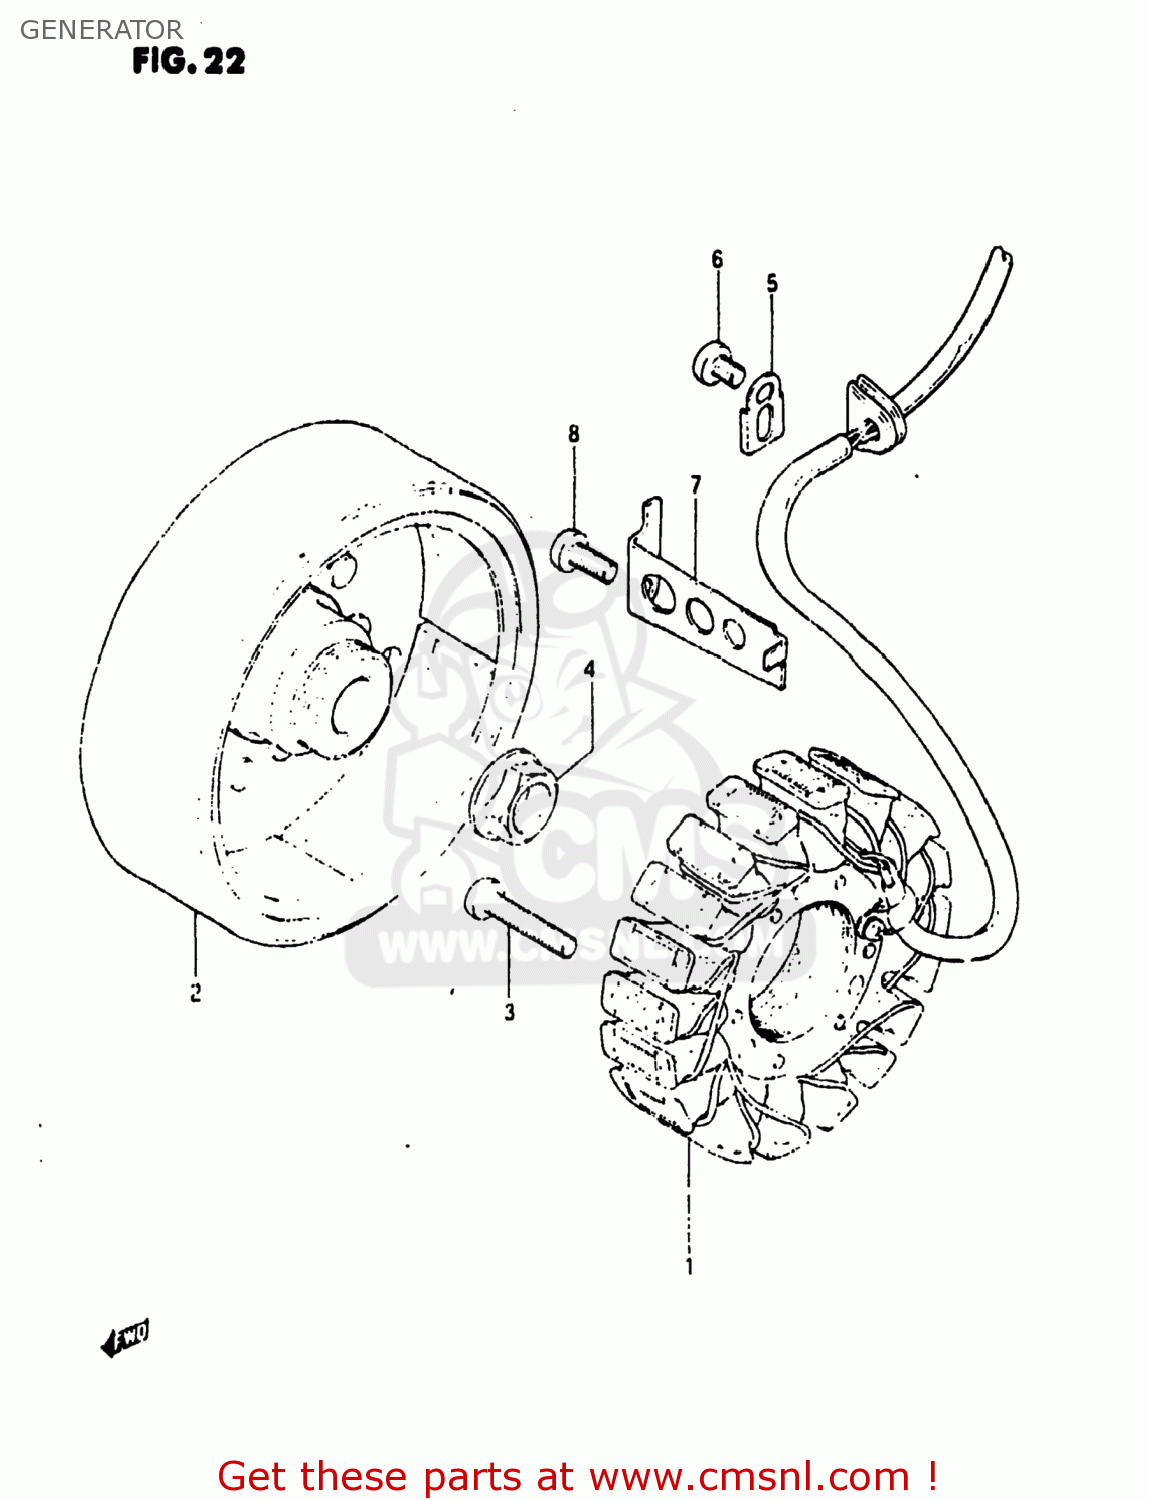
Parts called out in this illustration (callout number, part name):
1	STATOR ASSEMBLY
2	ROTOR ASSY
3	SCREW 6X30
4	NUT,GENERATOR ROTOR
5	CLAMP,GENERATOR LEAD WIRE
6	SCREW
7	CLAMP,GENERATOR LEAD WIRE
8	SCREW
